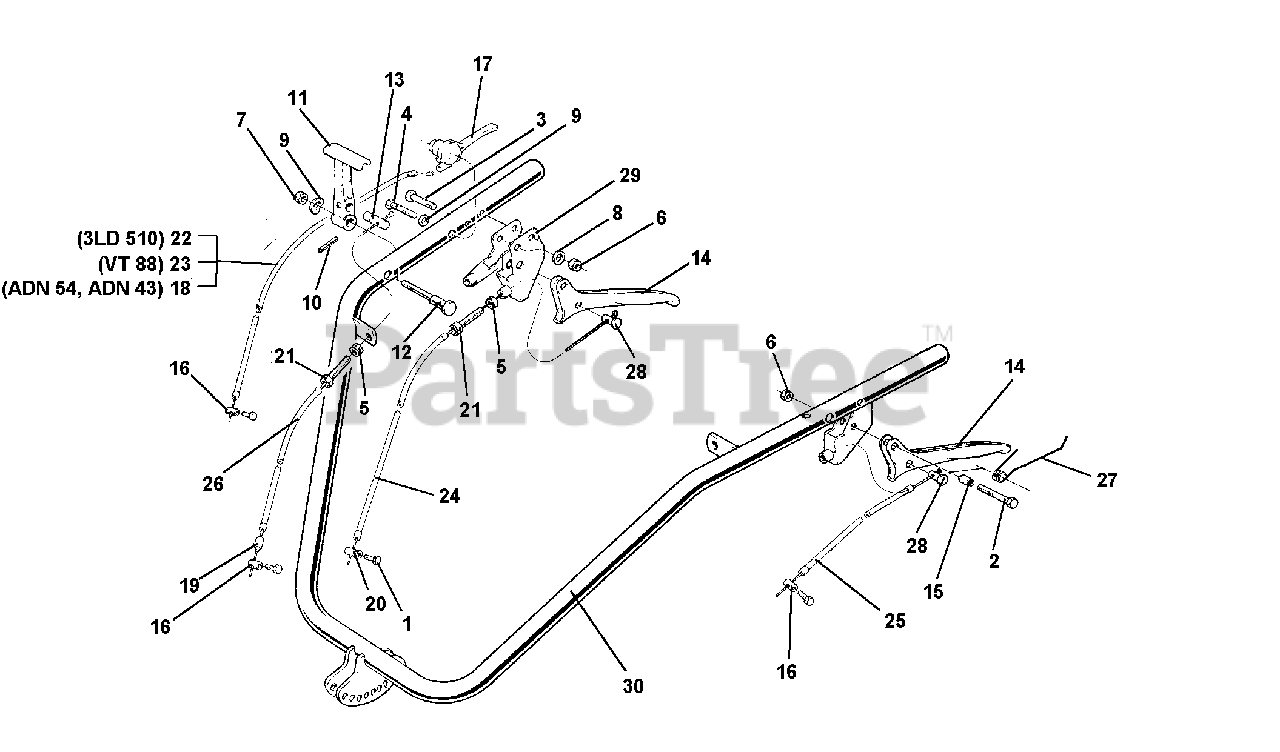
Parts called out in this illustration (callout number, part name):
1	SCREW TE M6 X 14
2	SCREW M6 X 25
3	SCREW M6 X 40
4	SCREW TE M8 X 40
6	NUT, SELF LOCKING M6
7	NUT, SELF LOCKING M8
8	WASHER, LOCK 6.4
9	WASHER, LOCK 8.4
10	PIN, LOCKING 4 X 20
11	LEVER DIFFERENTIAL LOCKING
13	DRILLED PIN
15	LEVER SPACER
16	CLAMP, CABLE
17	LEVER, ACCELERATOR
18	GAS WIRE AND SHEATH
19	END, SHEATH
20	PIN, CABLE CLAMP
21	SCREW, ADJUSTING M8
22	GAS WIRE AND SHEATH
23	CABLE & SHEATH ACCEL. L 1680
24	SHEATH CABLE
25	SHEATH CABLE
26	SHEATH CABLE
27	LEVER SPRING
29	COUPLING FOR DOUBLE LEVER
